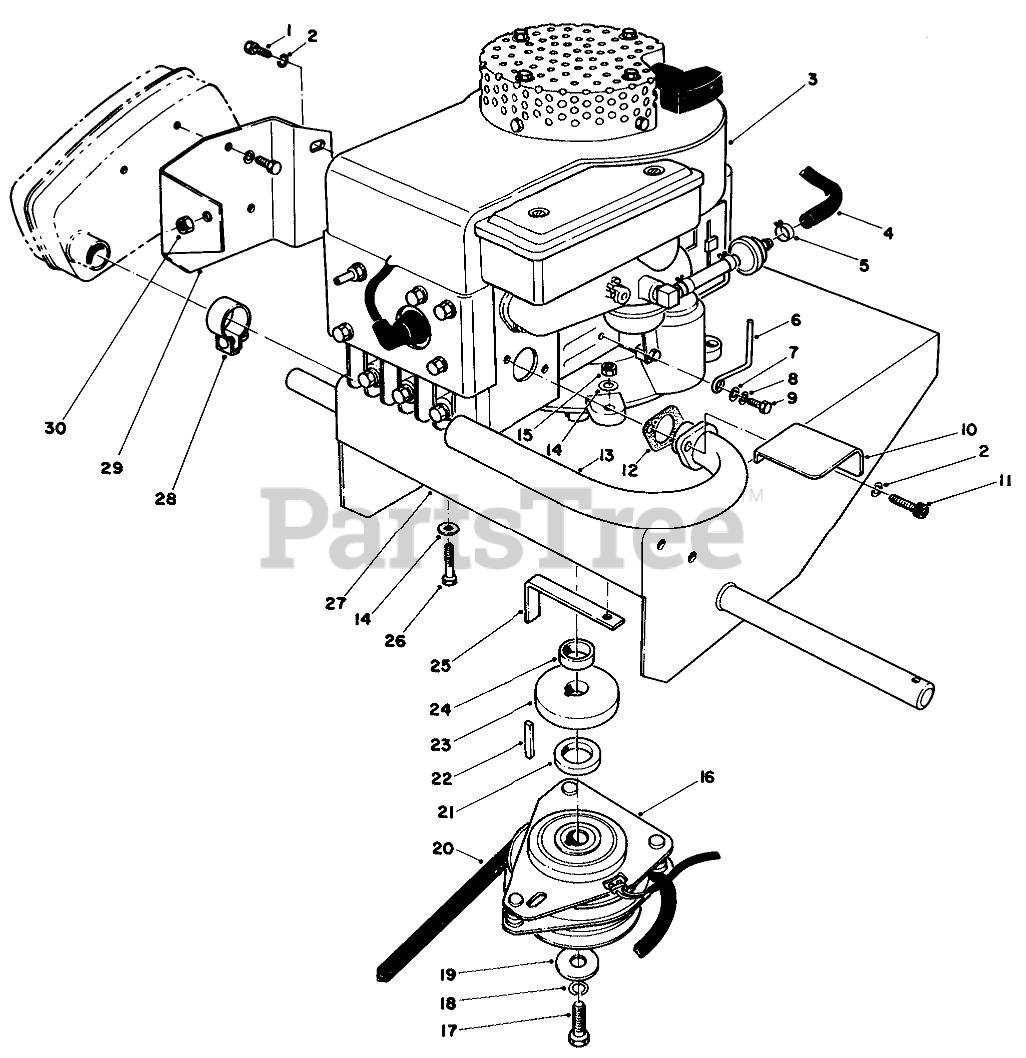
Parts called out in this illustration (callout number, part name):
1	SCREW-HH
2	WASHER-LOCK
3	Engine
4	HOSE-FUEL
5	Clamp
6	BRUSH GUARD
7	WASHER-FLAT
8	WASHER-LOCK
9	SCREW-HH
10	HEAT SHIELD
11	SCREW-HSH
12	Gasket
13	EXHAUST PIPE WA
14	WASHER-PLAIN
15	7/8X046 IN SNAP RING
16	Clutch Assembly-Deck
17	SCREW-HH
18	WASHER-LOCK
19	WASHER-CLUTCH
20	Belt-Drive
21	SPACER-LOWER
22	KEY-SQUARE
23	Pulley-Drive
24	Spacer-Upper
25	Retainer-Clutch
26	SCREW-HH
27	Frame
28	MUFFLER CLAMP
29	MUFFLER BRKT B
30	7/8X046 IN SNAP RING
31	Low Tone Muffler
